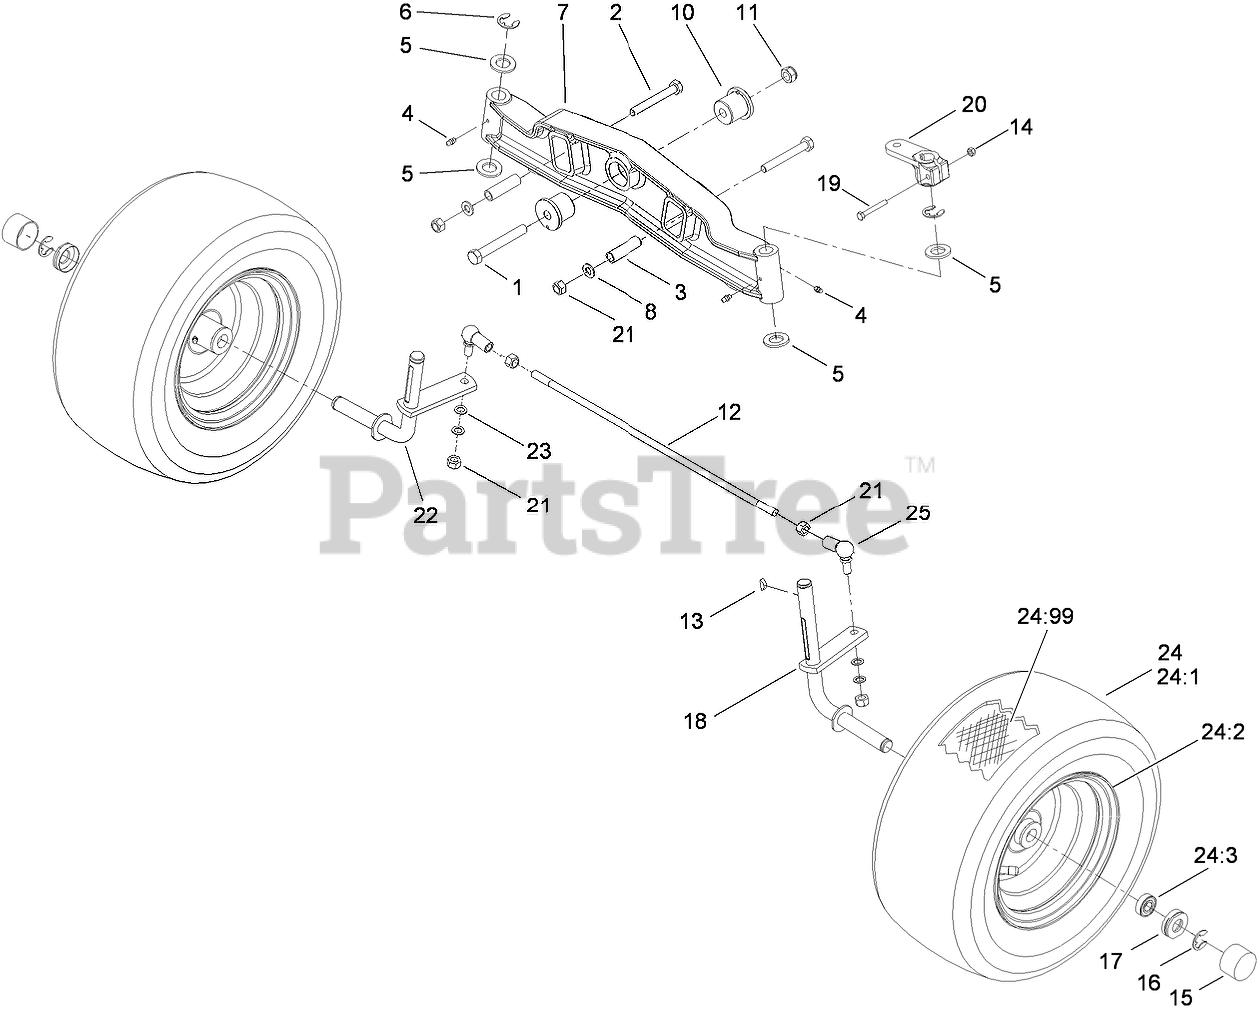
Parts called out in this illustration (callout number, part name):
1	SCREW-HH
2	SCREW-HH
3	SPACER
4	FITTING-GREASE
5	WASHER-FLAT
6	CLIP-SPRING
7	AXLE-FRONT
8	WASHER-FLAT
10	BUSHING-AXLE, FRONT
11	NUT-LOCKING, SELF
12	ROD-TIE, FRONT AXLE
13	KEY-WOODRUFF
14	NUT-LOCK
15	CAP-HUB
16	CLIP-SPRING
17	RETAINER-CAP, HUB
18	SPINDLE-FRONT, LEFT
19	SCREW-HH
20	LEVER-SPINDLE, STEERING
21	NUT-LOCK, NI
22	SPINDLE-FRONT, RIGHT
23	Washer
24	WHEEL ASM
24:2	RIM-FRONT
24:3	BEARING-WHEEL
24:99	TUBE-INNER
25	JOINT-BALL, ANGLE
